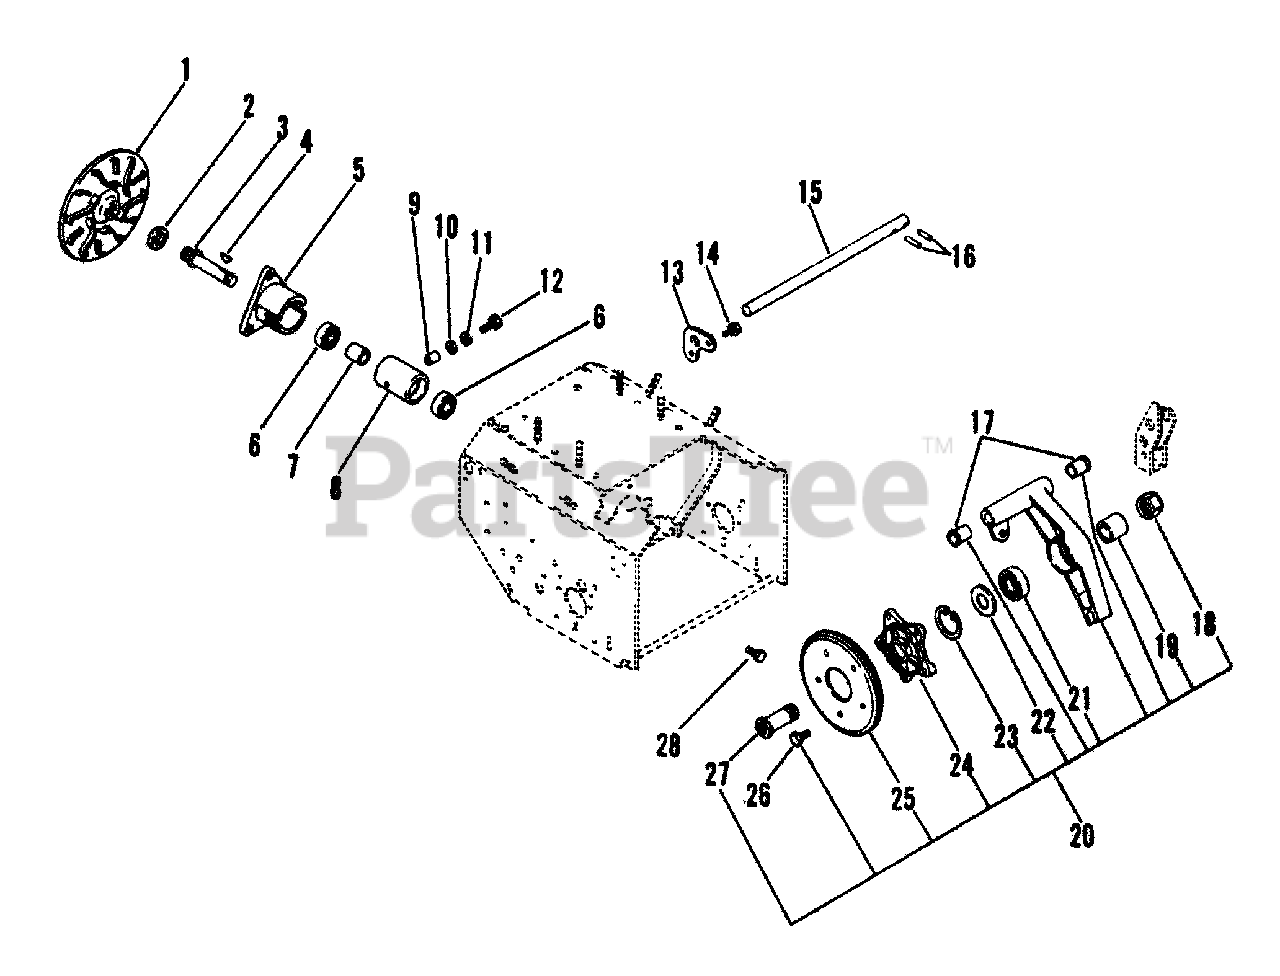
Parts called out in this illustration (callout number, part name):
1	DRIVE PLATE
2	DRIVE DISC SPACER 1.3X.76X.19
3	SPINDLE
4	KEY-WDRF .125X.500X.203 SAE 3
5	DRIVE SPINDLE HOUSING
5	HOUSING MOUNT
6	BRG-BALL .625X1.375X.44
7	BEARING SPACER
8	SPINDLE HOUSING
10	WSHR-FL-STL.344X.688X.065PL
11	WSHR-LK .312X.097 PL HVY
12	BLT-HEX .31-18X1.00 PL GR 2
13	SUPPORT, SHAFT
14	SCR-TAP .250-20X.37 HWH PL TR
15	CARRIER SHAFT
16	PIN-ROLL .156X1.00
17	BSHG-FLG .625X.750X.500X.875BR
18	NUT-LK-NYL .875-14
19	BSHG-SLV .882X1.250X.531
20	FRICTION WHEEL ASSEMBLY
21	BRG-BALL .876 X 1.750 X .50
22	WSHR-FL-STL .880X1.250X.062
23	RG-RTNG-INT 1.750X.062
24	DISC HUB
25	FRICTION DISC
26	SCR-TAP .312-18X.50 HWH PL TR
27	SPINDLE HUB
28	SCR-TAP .312-18X.50 HWH PL TR
